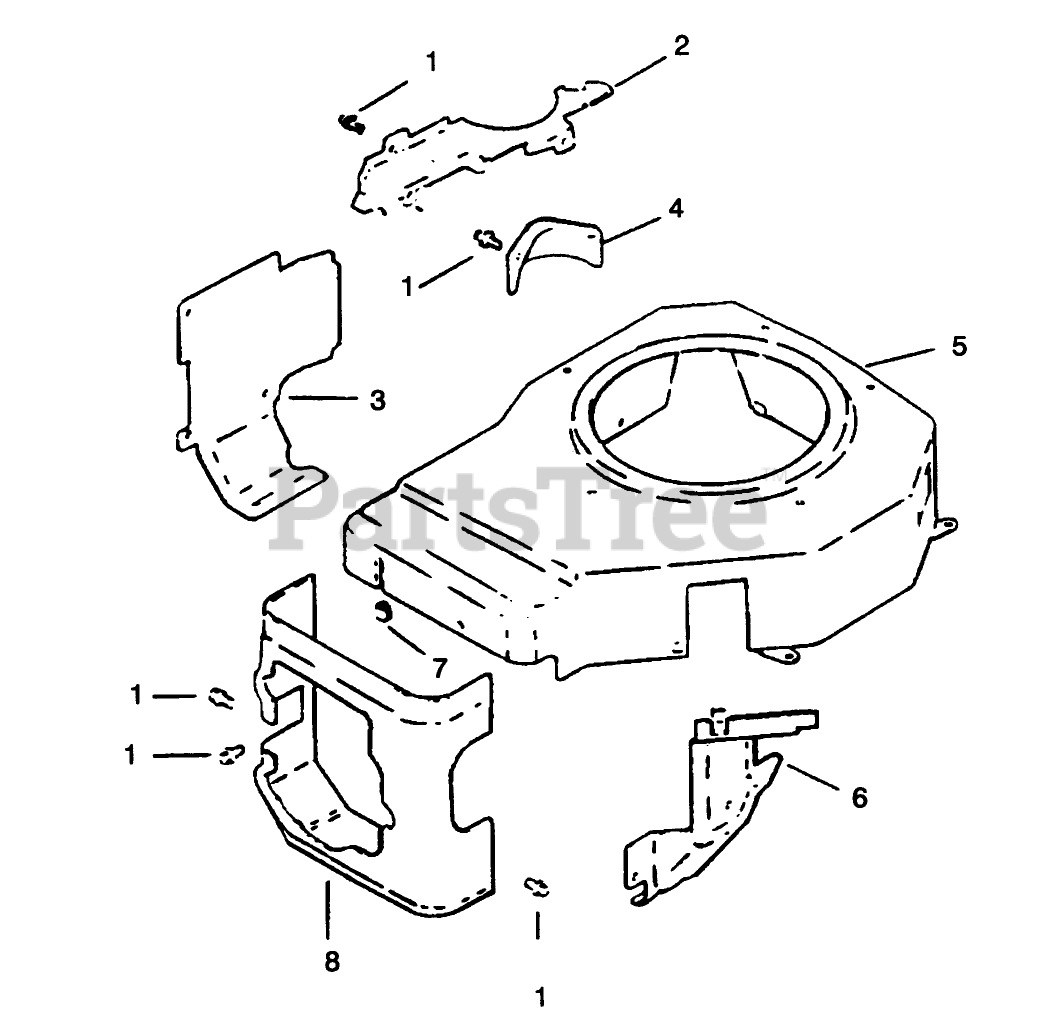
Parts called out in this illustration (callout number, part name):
2	Plate-Blower Housing (Only On: 72042,72043,72062,72063)
3	Baffle-Cylinder Barrel (Only On: 72042, 72063, 72062, 72043)
4	Cover-Starter
5	Housing-Blower
6	Baffle-Carburetor (Only On: 72042, 72043, 72062, 72063)
7	Grommet-Blower Housing (Only On: 72042, 72043, 72062, 72063)
8	Baffle-Cylinder Head
